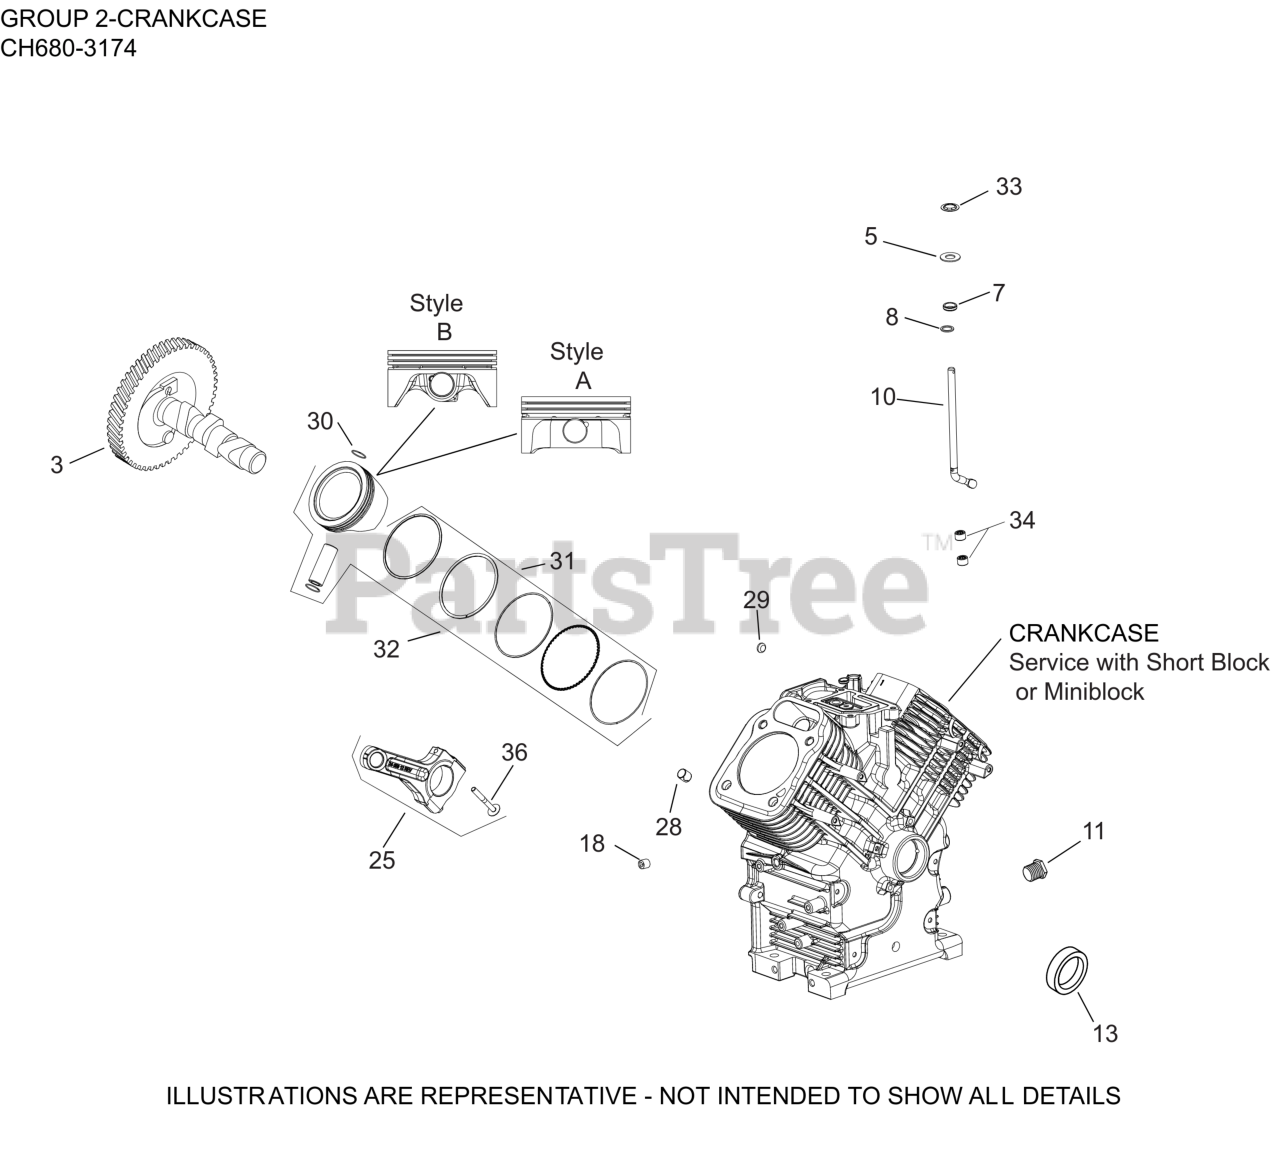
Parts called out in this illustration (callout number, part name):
3	KIT, CAMSHAFT
5	WASHER, FLAT 9 MM
7	SEAL, GOVERNOR CROSS SHAFT
8	WASHER, FLAT 11/32"
10	SHAFT, GOVERNOR CROSS
11	PLUG, HD PIPE 3/8"
13	SEAL, OIL (HELIX LIP)
18	PLUG, CTSK PIPE 1/8"
25	ROD, ASSEMBLY CONNECTING
28	PIN, LOCATING
29	PLUG, CUP
30	RETAINER, PISTON PIN
31	RING SET (STD) STYLE B
31	RING SET (.08) STYLE B
31	RING SET (.25) STYLE B
31	RING SET (.50) STYLE B
32	KIT, PISTON (STD) STYLE B
32	KIT, PISTON (.08) STYLE B-(#DSC)
32	KIT, PISTON (.25) STYLE B
32	KIT, PISTON (.50) STYLE B
33	RETAINER, RING
34	BEARING, NEEDLE
36	KIT, ROD BOLTS-(#25086677S)
